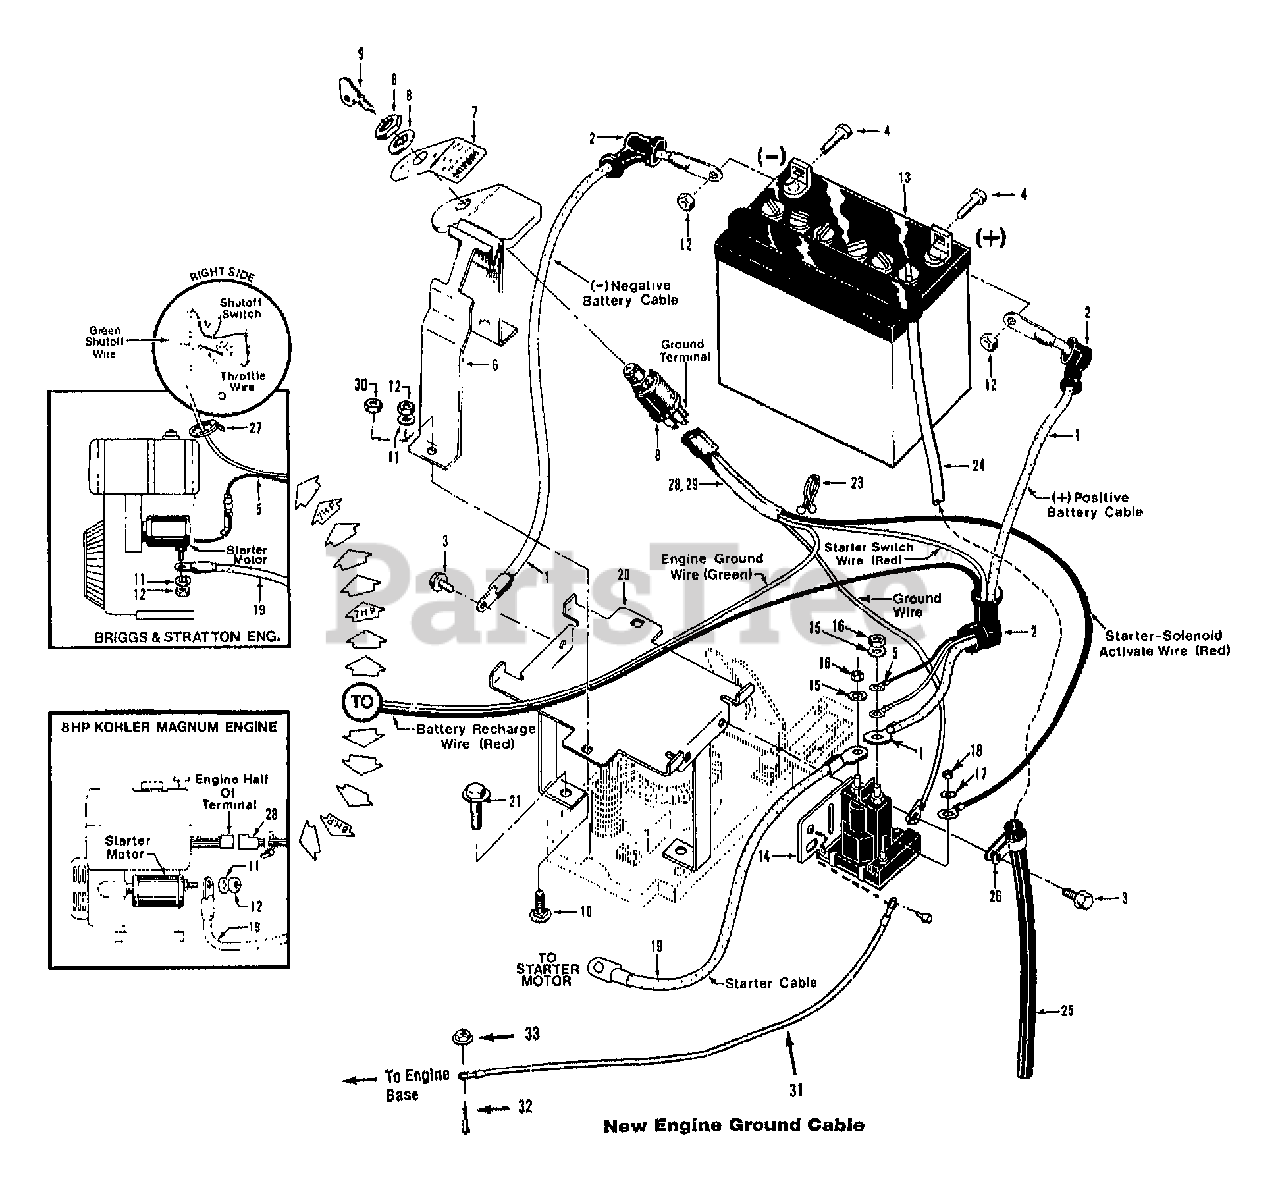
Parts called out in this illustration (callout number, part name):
1	CABLE-BATTERY 10"
2	BOOT-BATTERY CABLE
3	SCR-HWH 1/4-20 X .5 STH
4	SCR-HH 1/4-20X.625
5	WIRE-RECHARGE 5&7 BRIGGS
6	CLAMP-KEYSWITCH W/DECAL OPC (INCL. #1900944 DECAL)
7	DECAL-KEYSWITCH TILLER
8	ASSM-KEYSWITCH ELEC TLR (HARDWARE NOT AVAILABLE SEPARATELY FROM GARDEN WAY)
9	KEYS-IGN T/BLAZER 1 PAIR
10	SCR-CARR 1/4-20X1.25
11	WASHER-LK .25 ZP
12	NUT-HEX 1/4-20 ZP
13	BATTERY-12 VOLT HORSE
14	SOLENOID
15	WASHER-LK .312 ZP
16	NUT-HEX 5/16-24
17	WASHER-EXTERNAL TOOTH 1
18	NUT-HH M10-32X.125
19	CABLE-BATTERY 12"
20	BRKT-BATTERY OPC PNT
21	SCR-HFLK 3/8-16X1.50
22	THIS REF. NOT USED
23	TIE-TWIST LOCK
24	TUBE-VENT BATTERY/HSE
25	TUBING-RUBBER
26	CLAMP
27	TIE-RED
28	KIT-WIRE HARNESS ASSM
29	ASSM-WIRE HARNESS
30	NUT-HF/LK 1/4-20 ZP
31	CABLE-BATTERY 15"
32	SCR-HFLK 5/16-18X1.00 ZP (FOR KOHLER ENGINE ONLY)
33	NUT-HFLK 5/16-18 ZP (FOR KOHLER ENGINE ONLY)
